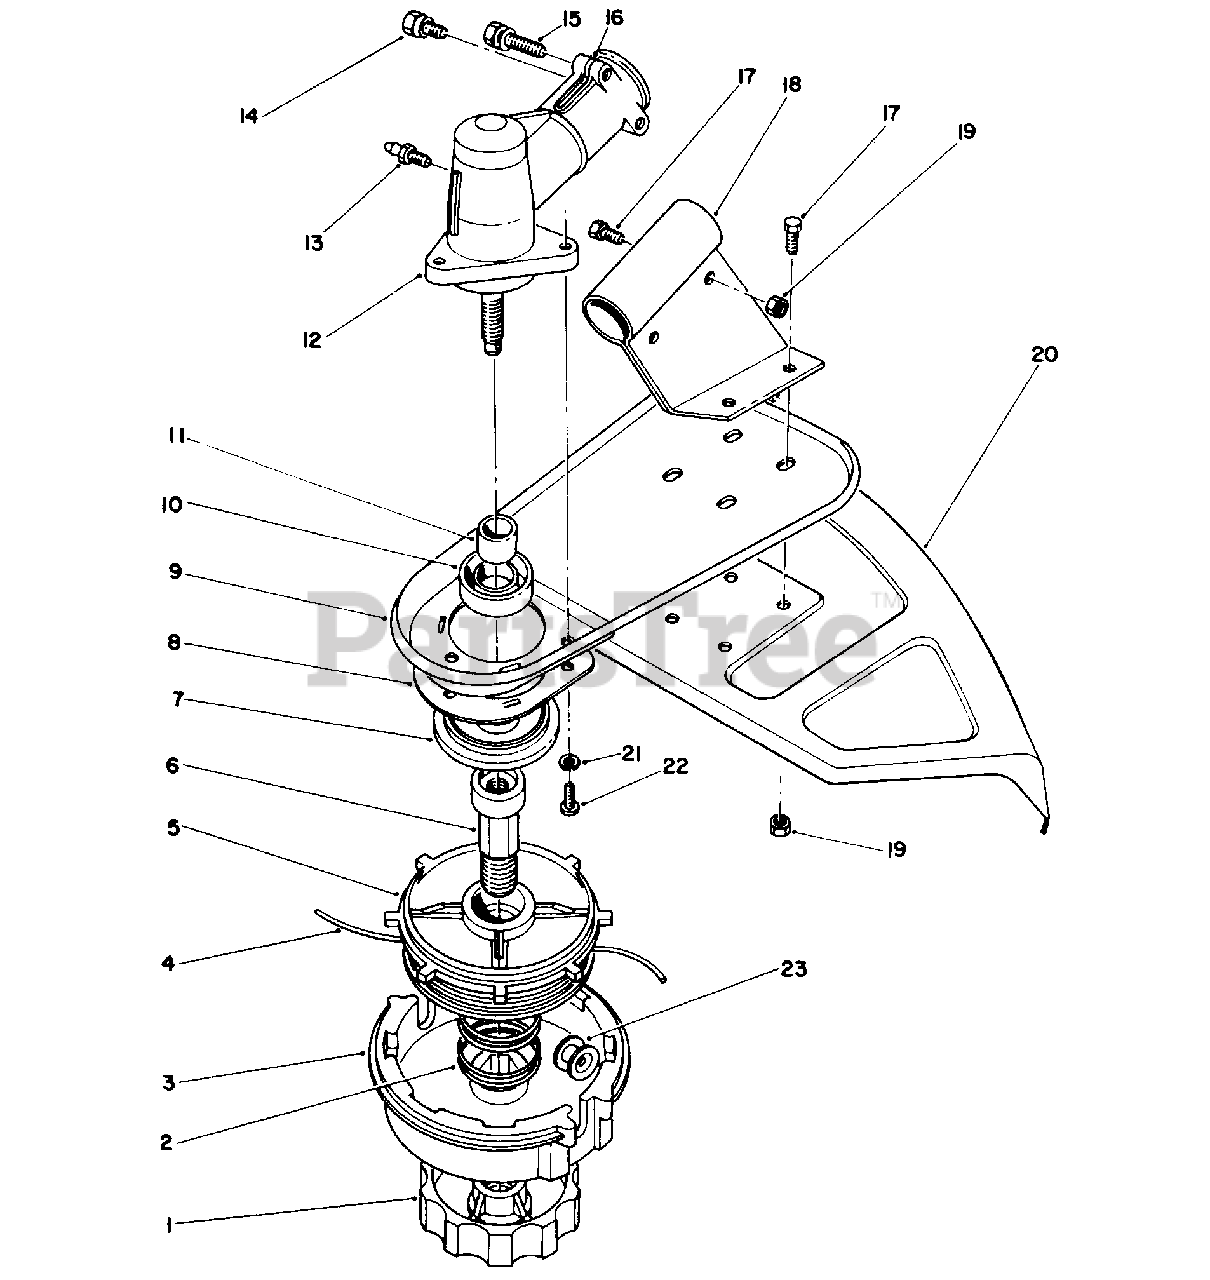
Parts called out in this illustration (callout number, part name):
1	Knob-L.H.
3	Spool Housing Assembly
5	Spool-Inner
7	Cap-Dust
8	Guard-Grass Wrap
9	Support-Shield
10	Seal-Oil
11	Sleeve-Spline
12	Gear Box Assembly (Incl. Ref. #10, 11, & 13-16)
13	Fitting-Grease
14	Screw-Hex. Hd.
15	Screw-Hex. Hd.
16	Washer-Flat
17	Screw-Hex. Hd.
18	Bracket-Shield
19	Nut-Lock
20	Shield-Grass
21	Washer-Lock
22	Screw-Guard
